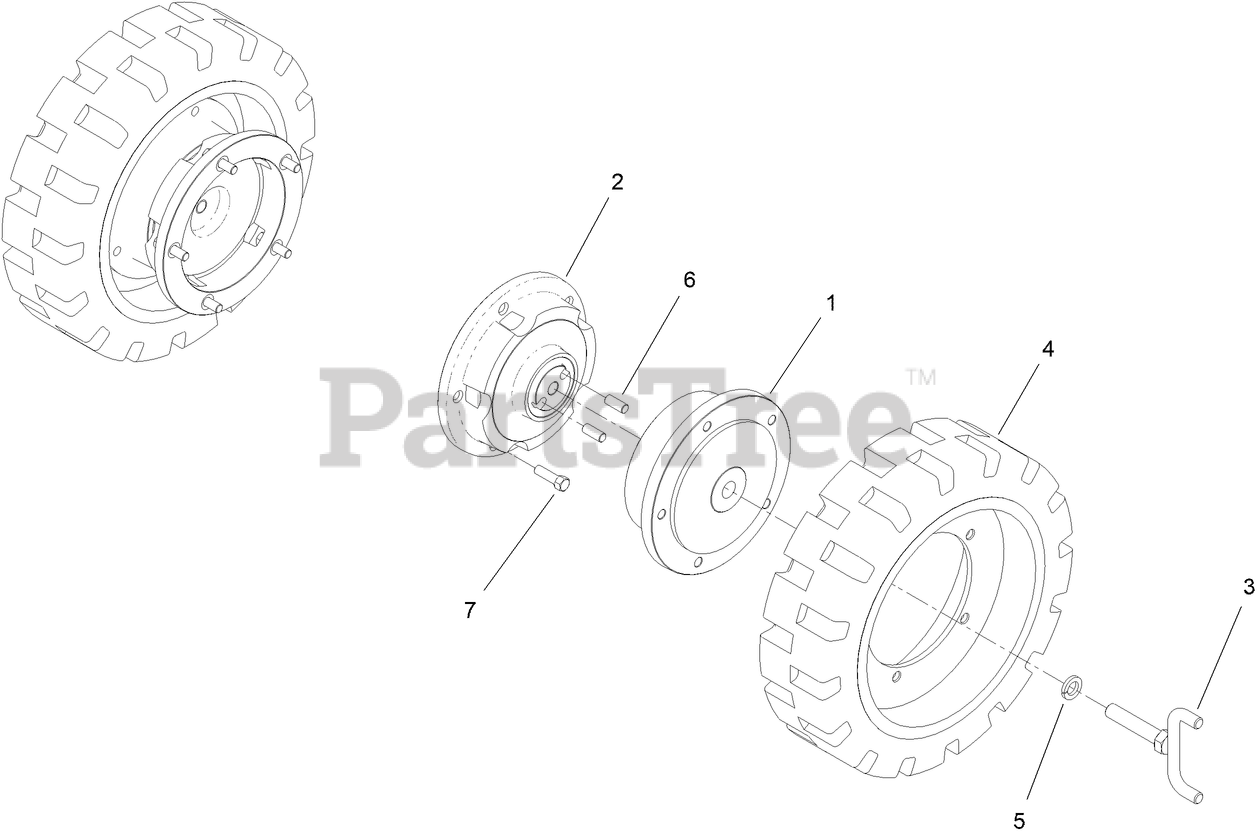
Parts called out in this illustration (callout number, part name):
1	SPACER-WHEEL, MACHINED
2	SPACER-WHEEL
3	QUICK RELEASE - WELDED
4	TIRE-SOLID
5	WASHER-LOCK
6	PIN-ROD, CONNECTING
7	SCREW-HH, LUG M12 X 1.50
